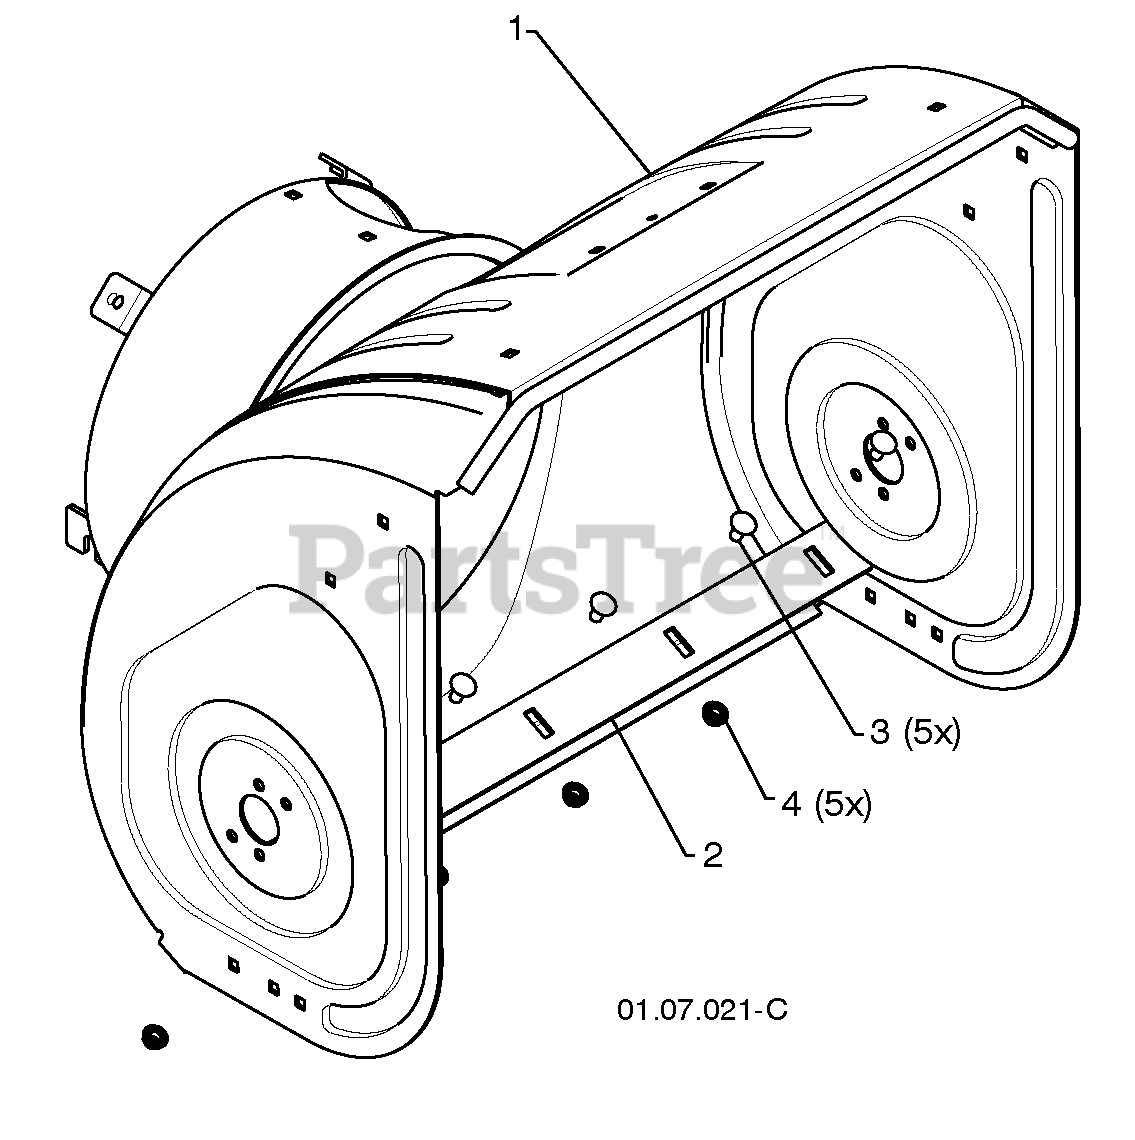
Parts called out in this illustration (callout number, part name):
1	AUGER HOUSING
2	SCRAPER BAR
3	CARRIAGE BOLT 5/16-18 X .625
4	NUT 5/16-18
